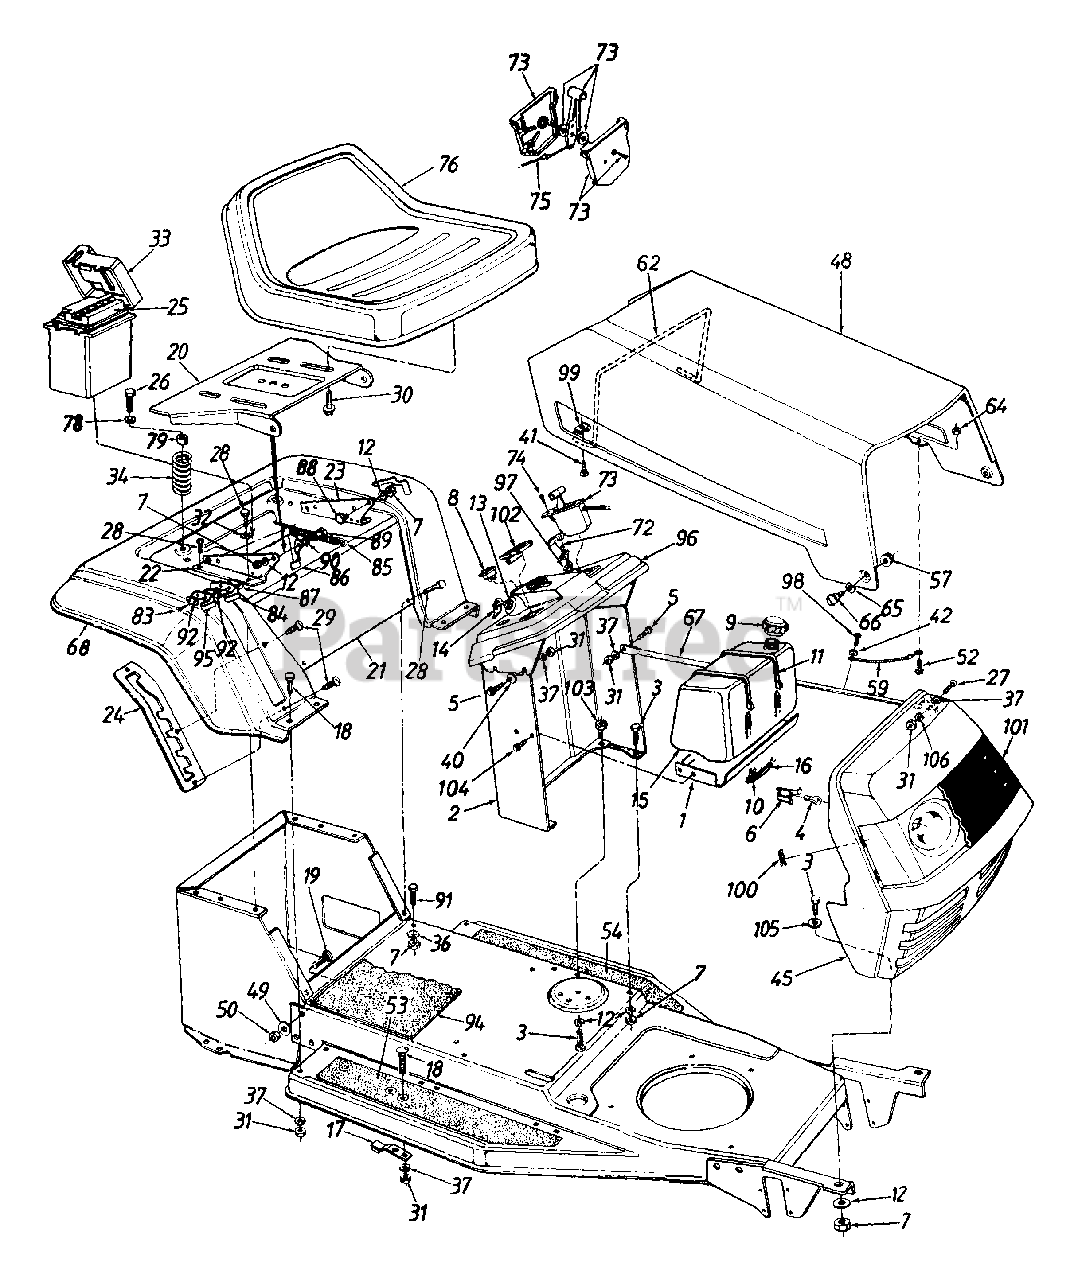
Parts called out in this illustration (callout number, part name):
4	Bulb
5	Hex Bolt 1/4 x .62" Lg.
6	Socket
7	Hex Nut 5/16-18 Thd.
8	Light Switch
9	Gas Cap
11	Cable Tie
12	L-Wash. 5/16" I.D."
13	Ignition Switch
14	Ignition Key
15	Fuel Tank
16	Gas Line 15" Long
17	Blade Brake Ass'y.
18	Carriage Bolt 1/4-20 x .62"
19	Ribbed Neck Bolt 3/8-24 x .8"
25	Battery
26	Hex Self-Tap Screw 5/6-18 x 1.25" Lg.
27	Truss Mach. Scr. 1/4-20 x .75" Lg.
28	Hex AB-Tap Scr. 5/16 x .75" Lg.
29	Torx Mach. AB-Tap Scr. 1/4 x .62" Lg.
30	Hex Self-Tap Scr. 3/8-16 x .75" Lg.
31	Hex Nut 1/4-20 Thd.
32	External L-Wash. 5/16" I.D.
33	Battery Box w/Cover
34	Compression Spring
36	Bell-Wash. 5/16" I.D.
37	L-Wash. 1/4" I.D.
40	Bell-Wash. .265" I.D. x .75"
41	Pan Hd. Scr. 10-24 x .75" Lg.
42	Fl-Wash. .218" I.D. x .62"
50	Hex L-Nut 3/8-24 Thd.
52	Truss Mach. Scr. #10-24 x .5" Lg.
53	Foot Pad - R.H.
54	Foot Pad - L.H.
57	Lock Nut 1/4-28 Thd.
64	Hex Sems Nut #10-24 Thd.
65	Spr. Wash. .39" I.D. x .62" O.D.
66	Shld. Bolt
72	Choke Control
73	Throttle Control Box
74	Truss AB-Tap Scr. #10 x .5"
75	Throttle Wire
76	Seat Assembly
78	Fl-Wash. .344" I.D. x .88" O.D.
83	Hex Tap Scr. #8 x .5" Lg.
84	Safety Switch (Seat)
85	Ext. Spring 5.31" Lg.
86	Seat Lift Brkt.
87	Insulator Boss Plate
88	Shld. Bolt .437" Dia. x .162" Lg.
89	Shld. Bolt .437" Dia. x .268" Lg.
90	Spr. Wash. .445" I.D. x .75" O.D.
91	Hex Wash. Hd. Scr. 5/16-18 x .62" Lg.
92	Insulator Plate
94	Center Foot Pad
95	Safety Switch (Seat)
97	Retainer Clip
98	Truss Mach. B-Tap Scr. #10 x .5" Lg.
99	Speed Nut
100	Internal Cotter Pin 5/16" Dia.
101	Lens
102	Ammeter
103	Hex Jam Nut 5/16-18 Thd.
104	Hex Wash. Hd. Tap Scr. 1/4-20 x .5" Lg.
105	Fl-Wash. .344" I.D. x 1" O.D.
106	Ext. L-Wash. 1/4" I.D.
